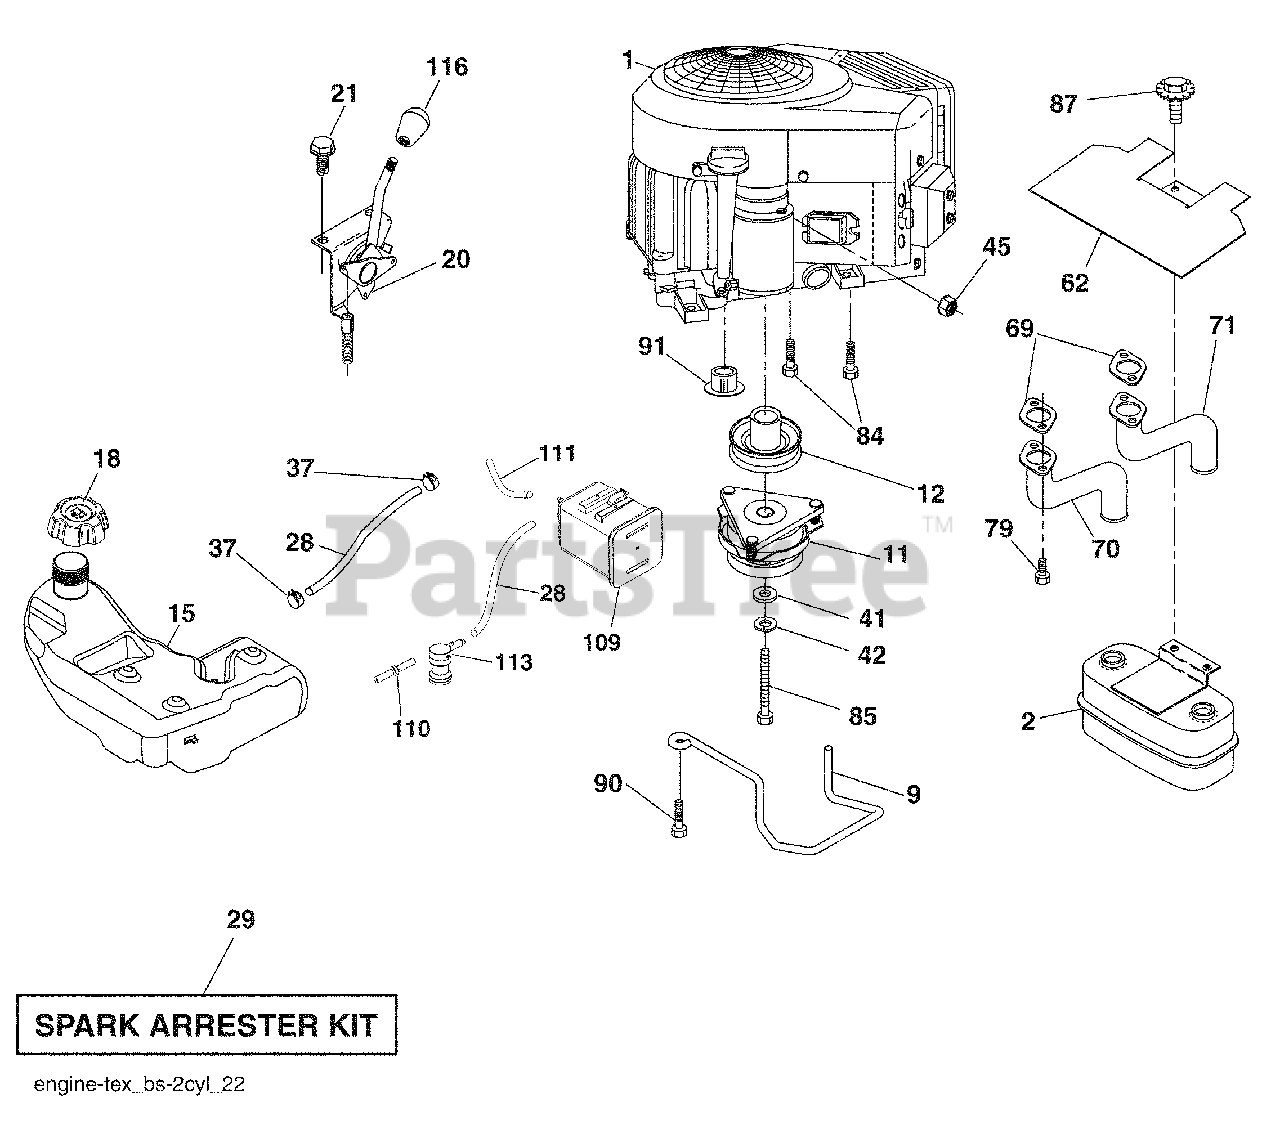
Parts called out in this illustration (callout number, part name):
9	Keeper Belt Engine
11	Clutch
12	Pulley Engine
15	Tank Fuel Asm.
18	Cap Asm
20	Control Throttle
21	Screw #10 x .750 BOS Thread
28	Fuel Line
29	Spark Arrester Kit
37	Clamp Hose
41	Washer 1-1/2 OD x 15/32 ID x .250
42	Washer Lock 7/16
45	Nut Keps Hex 1/4-20 unc
62	Heat Shield
70	Tube Exhaust LH
71	Exhaust Tube RH
79	Screw Socket HD 5/16-18 x 1
84	Screw 3/8-16 x 1-1/4
85	Bolt Hex 7/16-20 x 4 x Gr. 5-1.5 Thr
87	Bolt 5/16-18 unc x 3/4 w/Sems
90	Screw 3/8-16 x 1
109	Canister Carbon Filter Asm.
110	Valve Anti-Slosh
111	Purge Line
113	Valve Slant Cartrdg.
116	Knob Soft Touch
